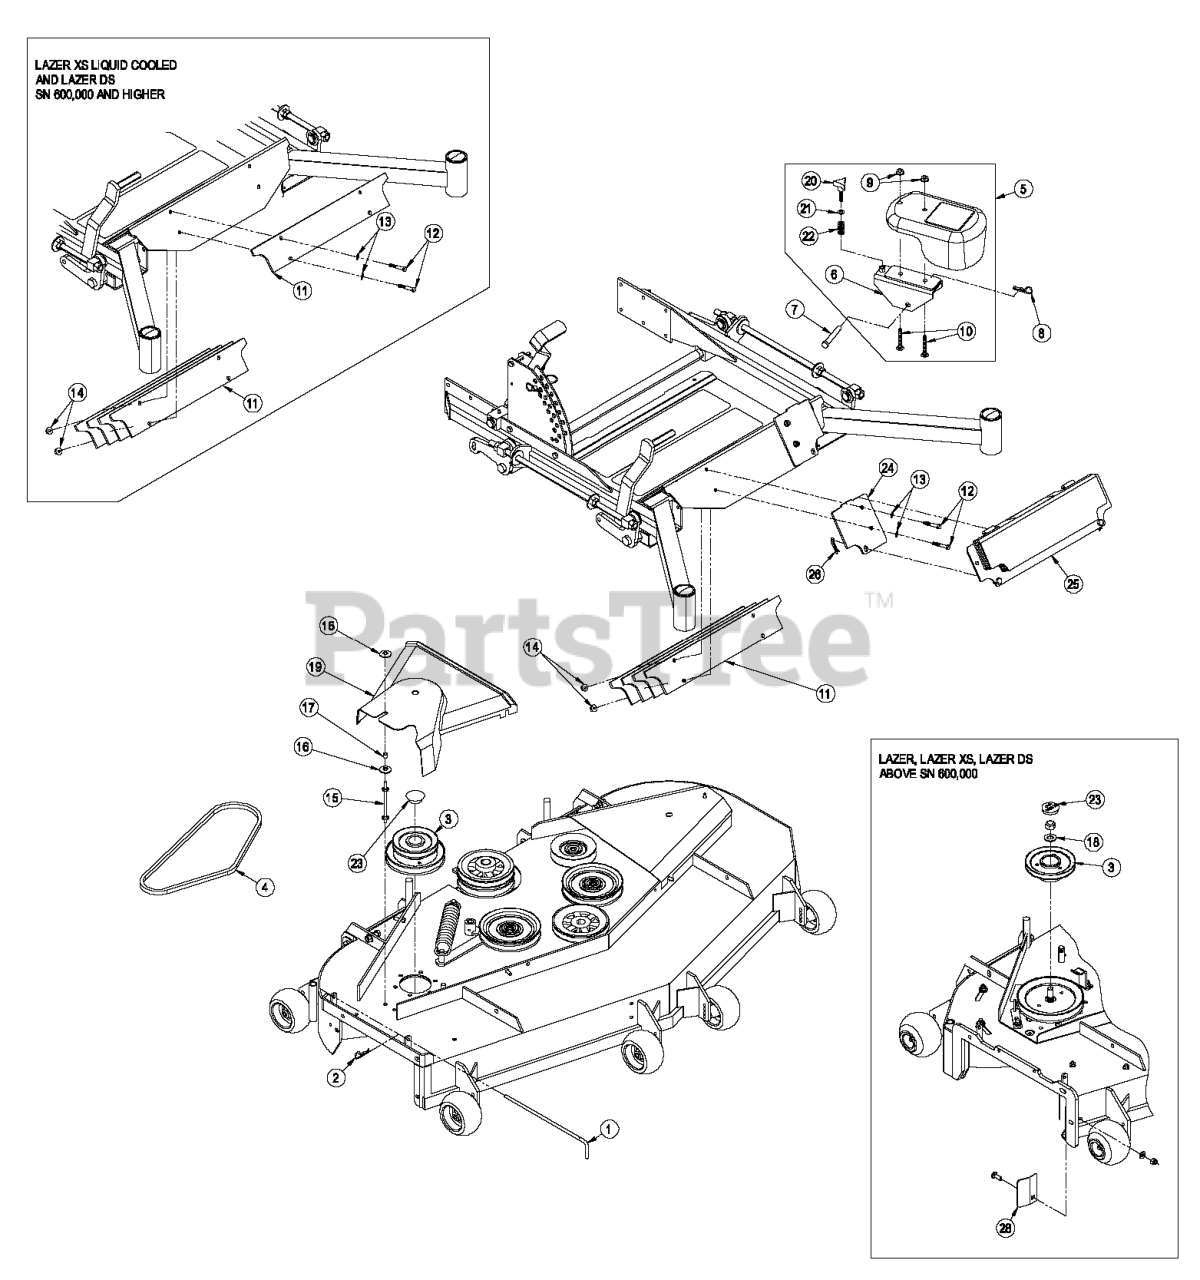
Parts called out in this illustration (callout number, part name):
1	PIN,CHUTE PIVOT
2	PIN-COTTER
3	JACKSHAFT, LZUV72
4	BELT, BLOWER DRIVE 72
5	ASM, WEIGHT 2.0" 43 POUND
6	WLD, BRACKET 2.0 ARM
7	PIN-CLEVIS
8	PIN-COTTER
9	NUT-HHF, WHIZ
10	BOLT-SQH
11	PLATE, WEIGHT
12	SCREW-HH
13	WASHER-PLAIN
15	STUD,BELT SHIELD 4 INCH
19	COVER, BELT 72
21	WASHER-FLAT
23	PLUG, BLACK NYLON 1.75
24	PLATE, WEIGHT MOUNTING
25	ASM, WEIGHT PLATE WITH DE
26	PIN-HAIR
